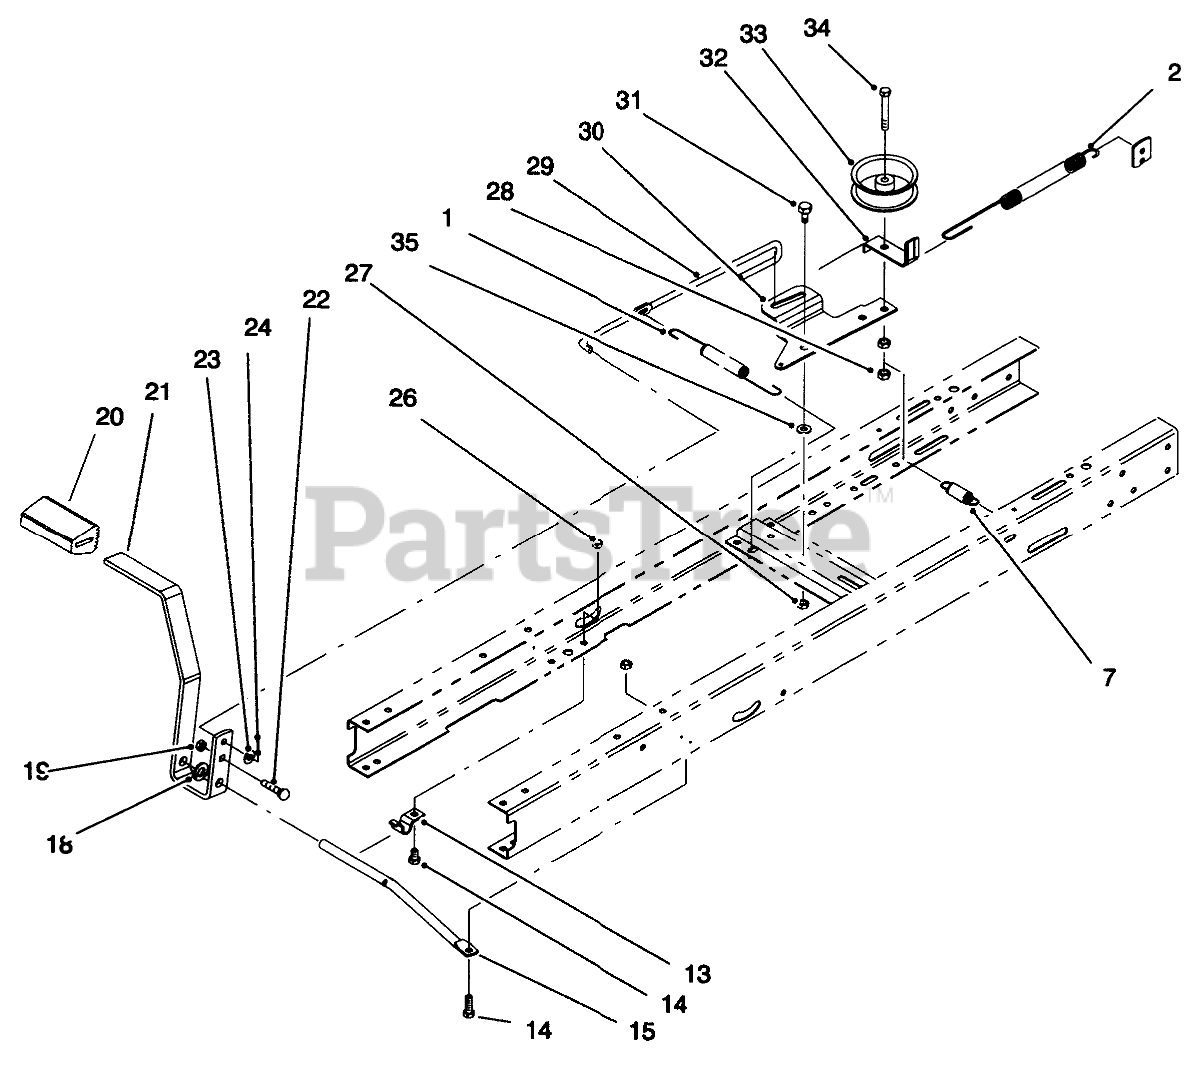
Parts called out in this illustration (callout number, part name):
1	SPRING-EXTENSION
2	BRAKE SPRING
7	SPRING-EXTENSION
13	CLAMP-PIVOT, SHIFT
14	SCREW-HH
15	ROD-PIVOT, PEDAL
18	WASHER-FLAT
19	NUT-LOCK, NI
20	PAD-PEDAL
21	Pedal-Clutch/Brake
22	SCREW-CARR
23	WASHER-PLAIN
24	PIN-COTTER
26	NUT-LOCK, NI
27	NUT-LOCK, NI
28	NUT-LOCK, NI
29	ROD-CLUTCH/BRAKE
30	ARM-IDLER
31	BOLT-SHOULDER
32	GUIDE-IDLER, BELT
33	Idler Pulley
34	SCREW-HH
35	WASHER-PIVOT
